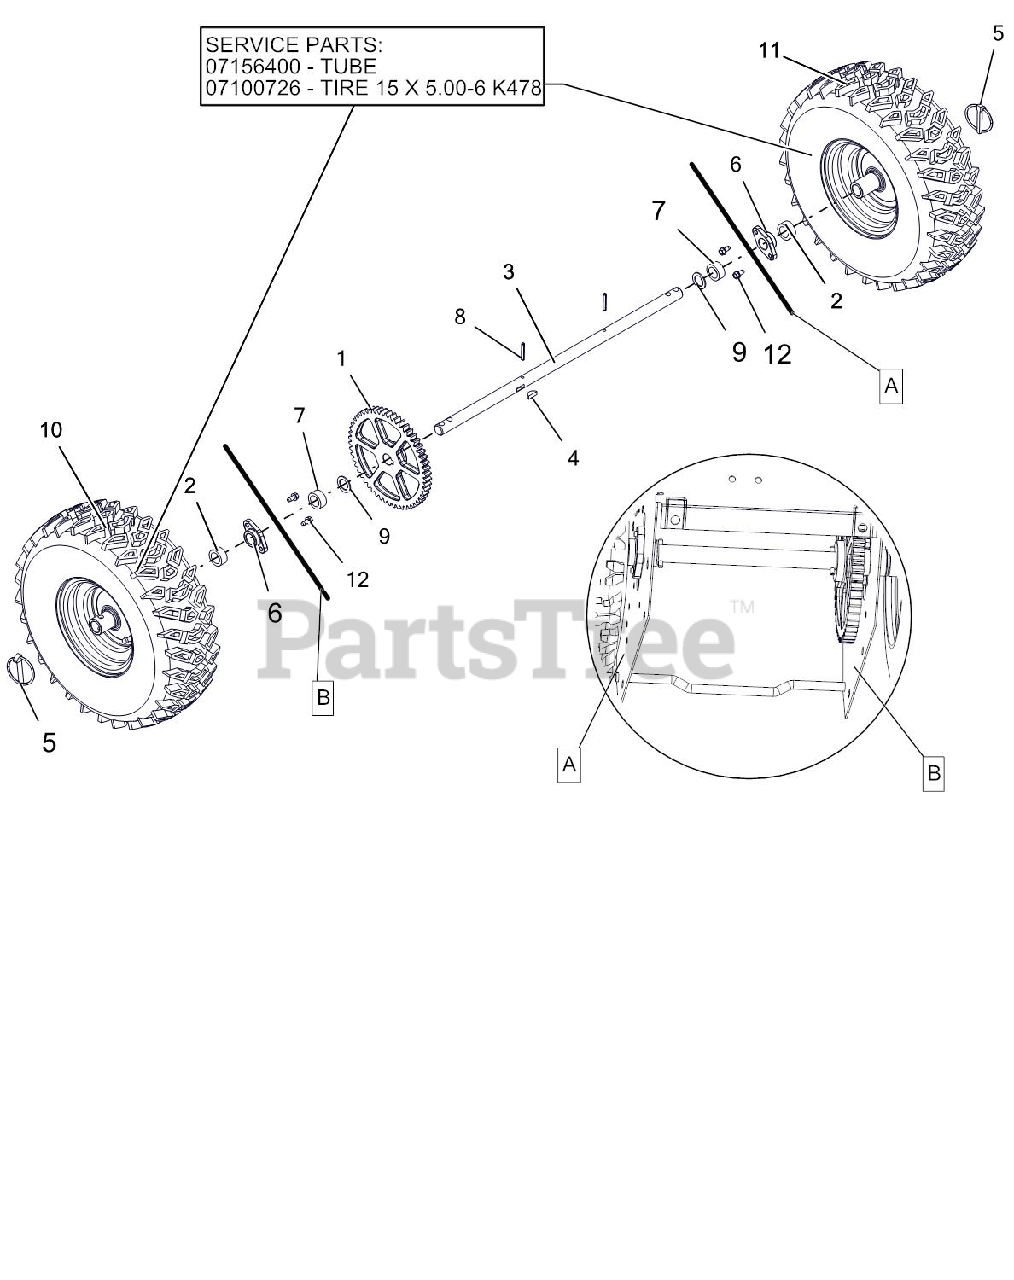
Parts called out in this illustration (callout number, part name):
1	SPUR GEAR, 54T .75ID X 6.75PD
2	BSHG-SLV .766 X 1.125 X .500
3	AXLE, COMPACT
4	KEY-WDRF .25X.750X.313 SAE91
5	PIN-LOK .31X1.75
6	BSHG .75X1.125X.65
7	BSHG-SLV .766 X 1.125 X .500
8	PIN-ROLL .188X1.25
9	WSHR-FL-STL.754X1.125X.062YWZC
10	TIRE/WHEEL,RH 15X5.00-6 PIN T2
11	TIRE/WHEEL,LH 15X5.00-6 PIN T2
12	SCR-TAP .25-20X.50 HWH TR YWZ
13	TUBE 15 X 5.00-6
13	TIRE, 15X5.00-6 K478
